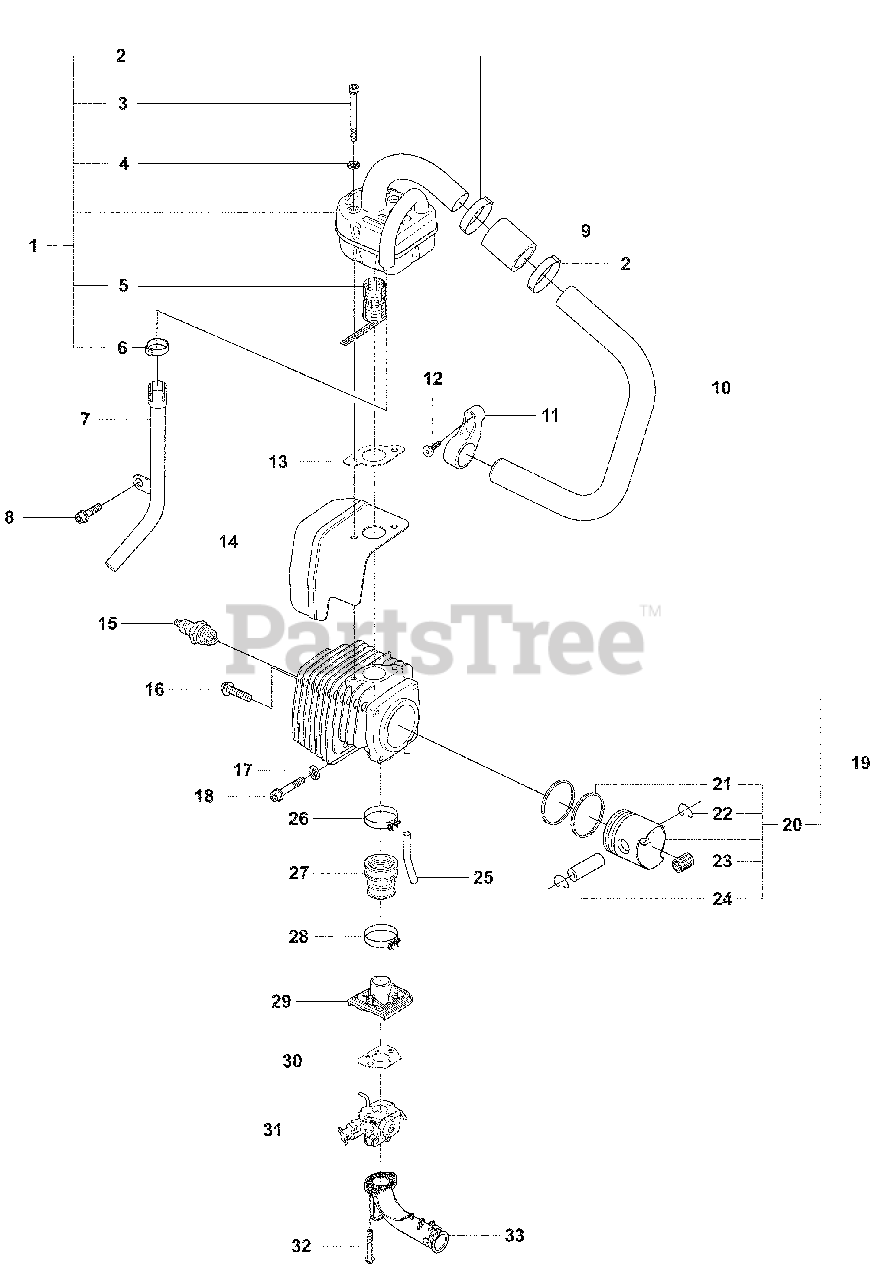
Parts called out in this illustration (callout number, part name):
4	Double Washer
5	SPARK ARRESTOR
10	PIPE
12	Screw, M5 X 14
15	Solid Spark Plug, BPMR7A
16	Screw, MC6S 5 X 25
17	Double Washer
18	Screw, M5 X 60
20	PISTON CPL 44MM
21	Piston Ring
23	Needle Bearing Piston Pin, 12 X 1
24	PISTON BOLT
25	Fuel Hose
26	Clamp
27	INLET TUBE
28	Clamp
31	Carburetor
33	PIPE
33	INLET BEND 5MM WIRE
